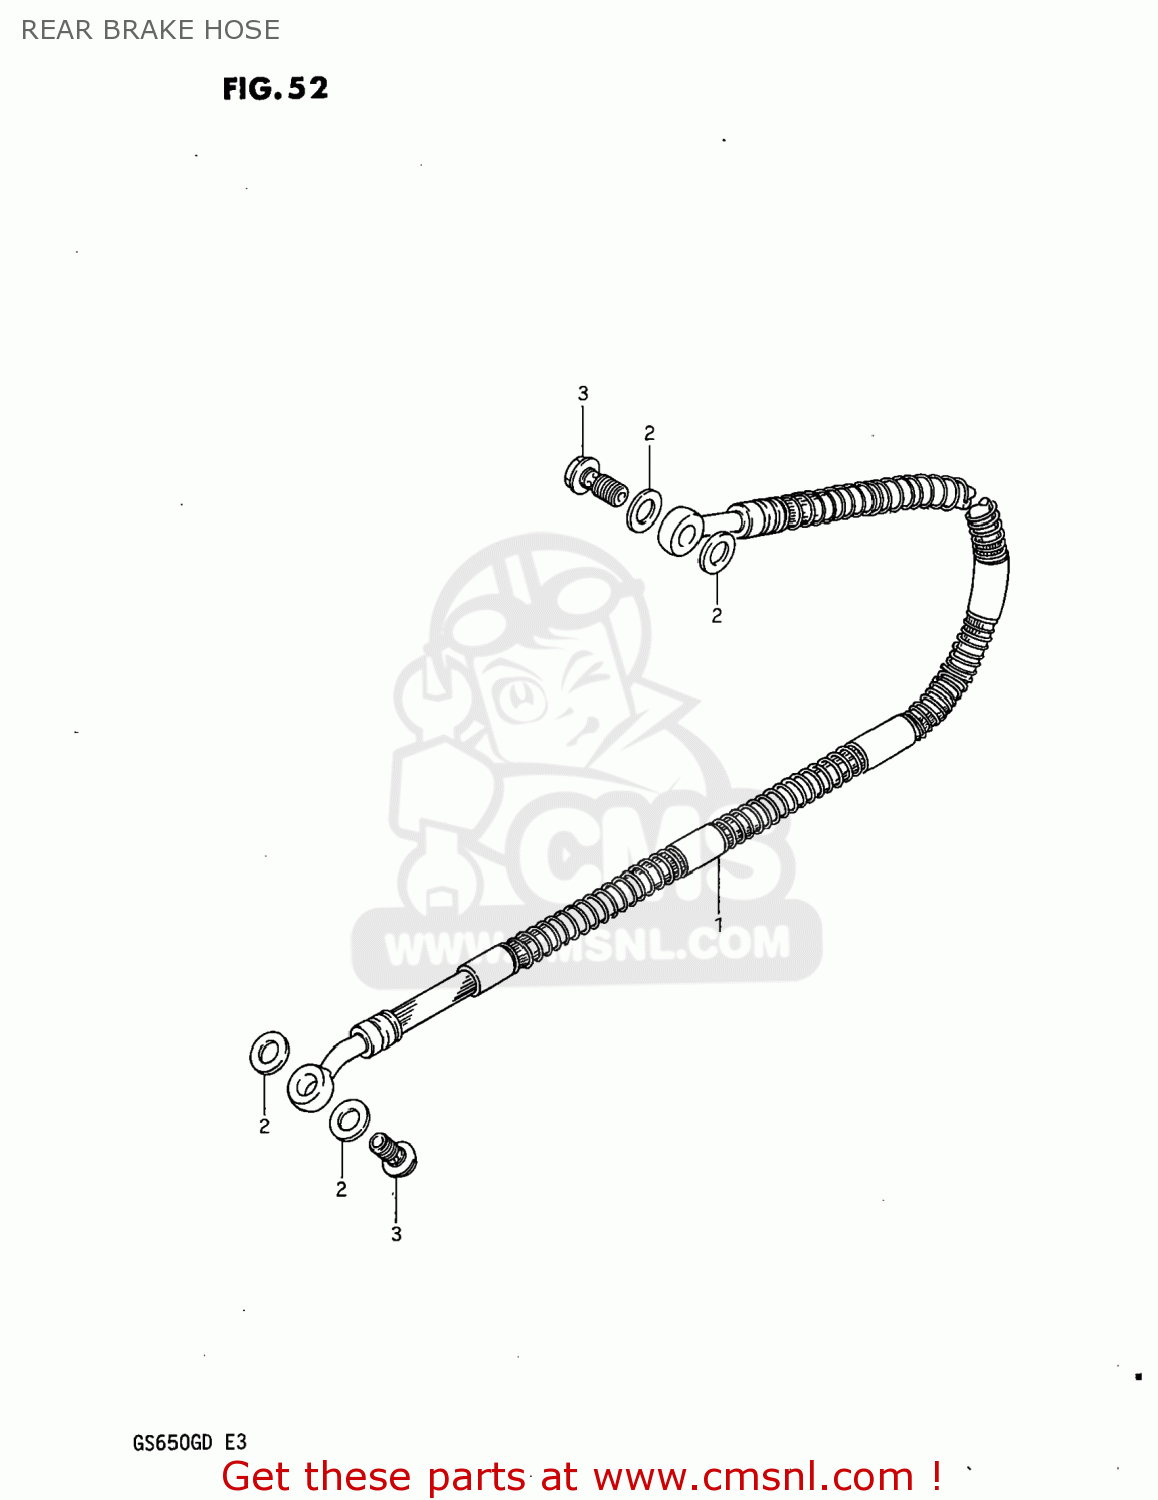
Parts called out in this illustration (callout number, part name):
1	HOSE,REAR BRAKE
2	WASHER
3	BOLT,UNION
